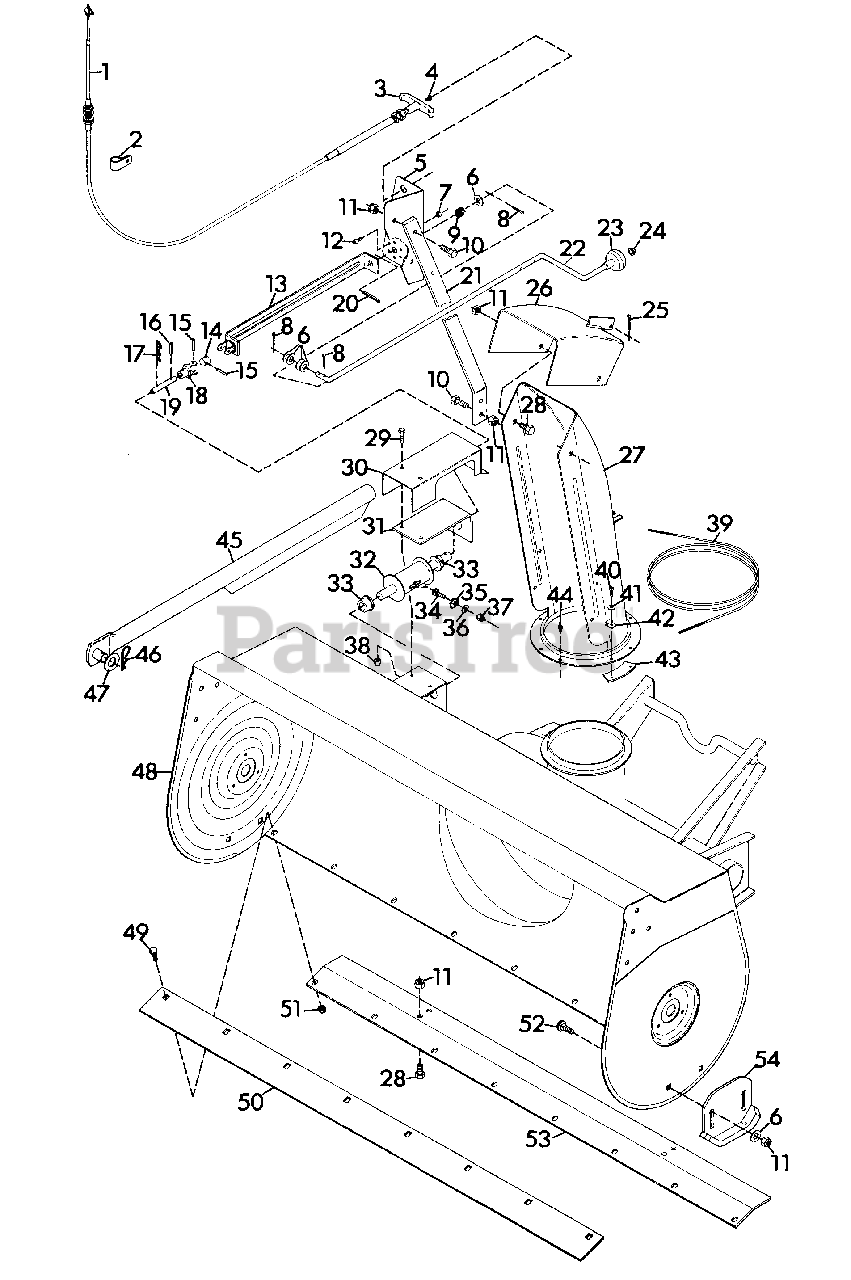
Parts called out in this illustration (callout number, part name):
1	CABLE, CONTROL
2	CLAMP, NYLON
3	HANDLE, TEE
4	SCREW, MACHINE 10-32X.50
5	BRACKET, CONTROL
6	WASHER, FLAT .406X.812X.065
7	NUT, #10-24 HEX
8	PIN, COTTER .06X1.00
9	COMPRESSION SPRING
10	BOLT, HEX 3/8-16X1.00
11	NUT, LOCK 3/8-16
12	SCREW, #10-24X.375 CAP
13	BRACKET, SLOTTED
14	BLOCK, UNIVERSAL
15	PIN, SPRING. 187X1.000
16	PIN, SPRING .125X.750
17	HAIR PIN, INTERNAL
18	HALF, UNIVERSAL
19	ROD, CONNECTOR
20	PIN, SPRING .187X1.500
21	BAR, CRANK BRACKET
22	ROD, CONTROL
23	KNOB
24	CAP
25	PIN, COTTER .09X.75
26	DEFLECTOR, CHUTE
27	CHUTE, DISCHARGE
28	BOLT, HEX 3/8-16X.75
29	BOLT, HEX 1/4-20X1.00
31	BRACKET, SPOOL
32	SPOOL
33	BUSHING, NYLON .76X1X.6 FLG.
34	BOLT, 1/4-20X.625 RD HD SQ NK
35	WASHER, LOCK SPECIAL 5/16 I.D.
36	WASHER, FLAT .281X.625X.065
37	NUT, HEX 1/4-20
38	NUT, LOCK 1/4-20
39	CABLE
40	SCREW, TAPTITE 10-24X.75
41	WASHER, FLAT .219X.438X.049
42	CLAMP, CABLE
43	CLAMP, CHUTE
44	SCREW, TAPTITE 10-24X.375
45	WELDMENT, PUSH ROD
46	COTTER, HAIR PIN
47	WASHER, FLAT .812X1.469X.134
48	40" SNO THRO HOUSING
48	48" SNO THRO HOUSING
49	BOLT, CARRIAGE 5/16-18X.875
50	SCRAPER BLADE - 40"
50	SCRAPER BLADE - 48"
51	NUT, LOCK 5/16-18
52	BOLT, 3/8-16X1.00 RD HD SQ NK
53	SCRAPER BLADE BRACE - 40"
53	SCRAPER BLADE BRACE - 48"
54	RUNNER, SKID SHOE
NS	DECAL, CHUTE CRANK
NS	DECAL, GRAVELY LOGO
NS	DECAL, DANGER FOOT
NS	DECAL, DANGER HAND
